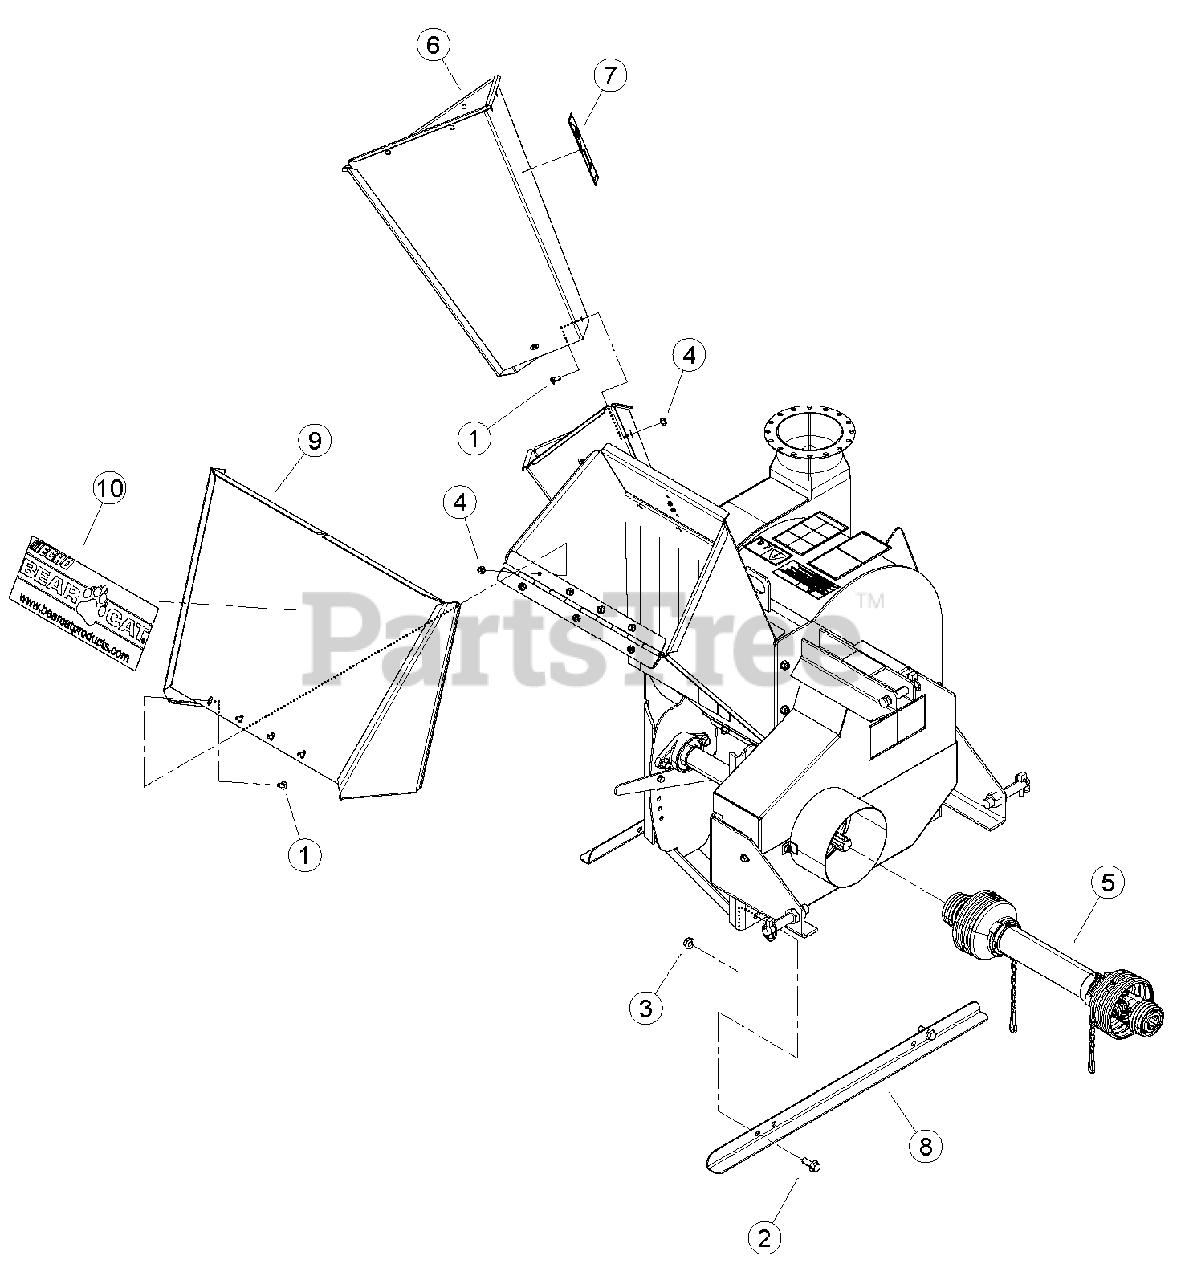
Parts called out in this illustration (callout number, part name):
1	BOLT, 5/16 X 3/4" GR5 CRG NC ZP
2	BOLT, 1/2 X 1-1/4" SERRATED FLANGE
3	NUT, 1/2 SPIRAL LOCK NC ZP
4	NUT, 5/16-18 NYLOCK FLANGE
5	DRIVELINE, 22.0/30.4" 1-3/8 SPL
6	ASSEMBLY, COMM CHUTE EXTENSION W/ DECAL
7	DECAL, BLADE DANGER ISO
8	LEG, C/S SUPPORT
9	ASSEMBLY, CHUTE EXTENSION
10	DECAL, BEARCAT WEB
